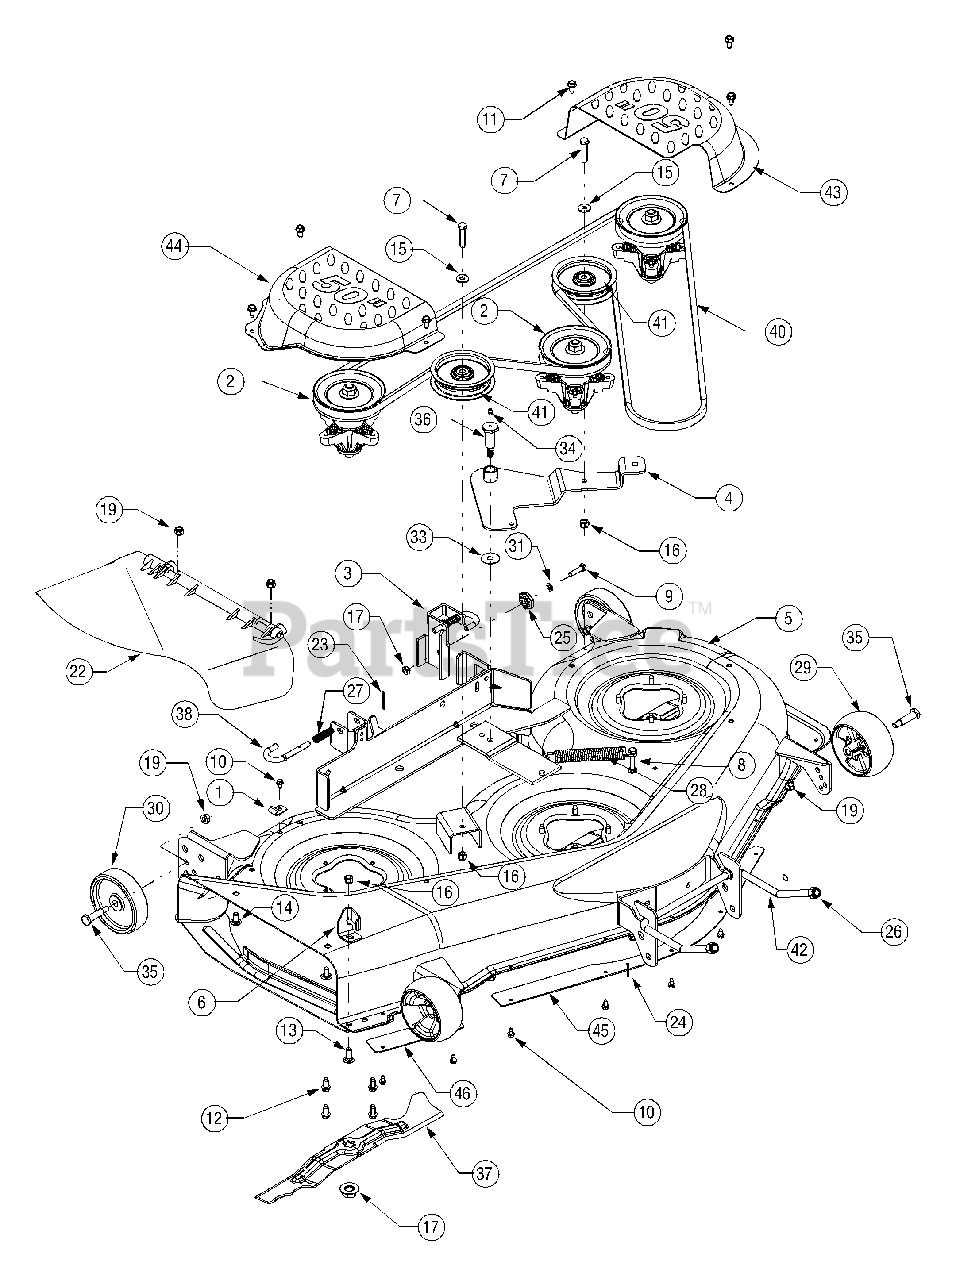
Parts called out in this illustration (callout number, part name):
1	Hook, Retainer
2	Spindle Assembly
7	Screw, 3/8-16, 1.75
8	Screw, 5/16-18 x 2.00
9	Screw, 5/16-18, 1.25, Gr5
10	Screw, 1/4-20 x 0.5
11	Screw, 5/16-18 x.625
12	Screw, 5/16-18 x .75
13	Screw, Carriage, 3/8-16 x 1.0
14	Screw, Carriage, 3/8-16 x .75
15	Washer, Flat, .406 x .875 x .059
16	Nut, Nylon Lock, 3/8-16
17	Nut, Hex, Flange, 5/8-18
18	Nut, Nylon Lock, 5/16-18
19	Nut, Flange Lock, 3/8-16
20	Nut, Hex, 5/16-18, Gr5
21	Nut, 7/16-14
22	Chute Assembly, Side Discharge
23	Pin, Cotter, 1/8 x 1.25
24	Pin, Cotter, 3/32 x 1.25
25	Deck Adjustment Gear
26	Lock Nut, Hex, 1/2-13, Nylon
27	Spring, Compression, .531 x 1.75
28	Spring, Extension, .94 x 6.74
29	Deck Wheel, 5.0
30	Deck Wheel, 5.0
31	Washer, Lock, 5/16, Regular Duty
32	Washer, Bell, .45 x 1.0 x .062
33	Washer, Flat, .442 x 1.38 x .060
34	Fitting, Lube, 3/16
35	Shoulder Screw
36	Screw, Shoulder, .68 x 1.59
37	Blade
38	Rod, Handle, Deck Release .375 Dia
39	Spacer, .550 x .755 x 1.1
40	Belt, V-Type, Aramid
41	Pulley, Idler, 3.5"
42	Rod, Deck Adjustment
